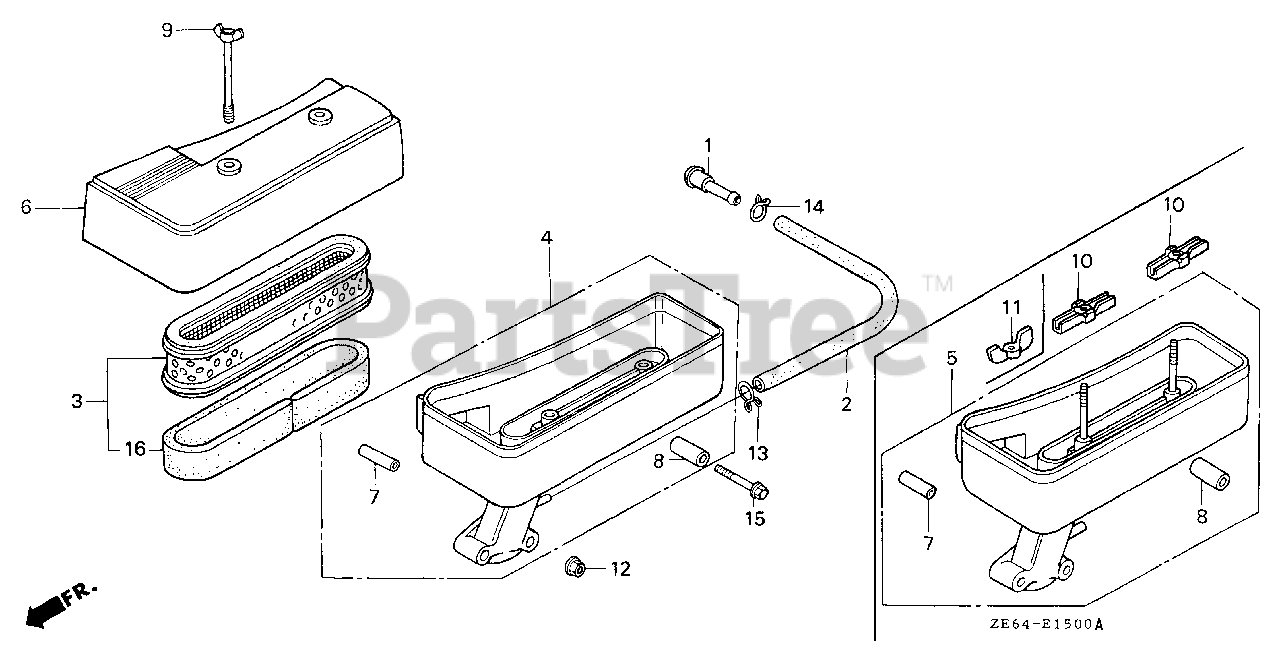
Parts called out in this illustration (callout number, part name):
1	JOINT, TUBE
2	TUBE, BREATHER
3	ELEMENT, AIR CLEANER
4	CASE SET, AIR CLEANER
6	COVER, AIR CLEANER
7	COLLAR, AIR CLEANER
8	COLLAR B, AIR CLEANER
9	BOLT, ELEMENT SETTING
12	NUT, FLANGE (6MM)
13	CLIP, TUBE (B12)
14	CLIP, TUBE
15	BOLT, FLANGE (6X35)
